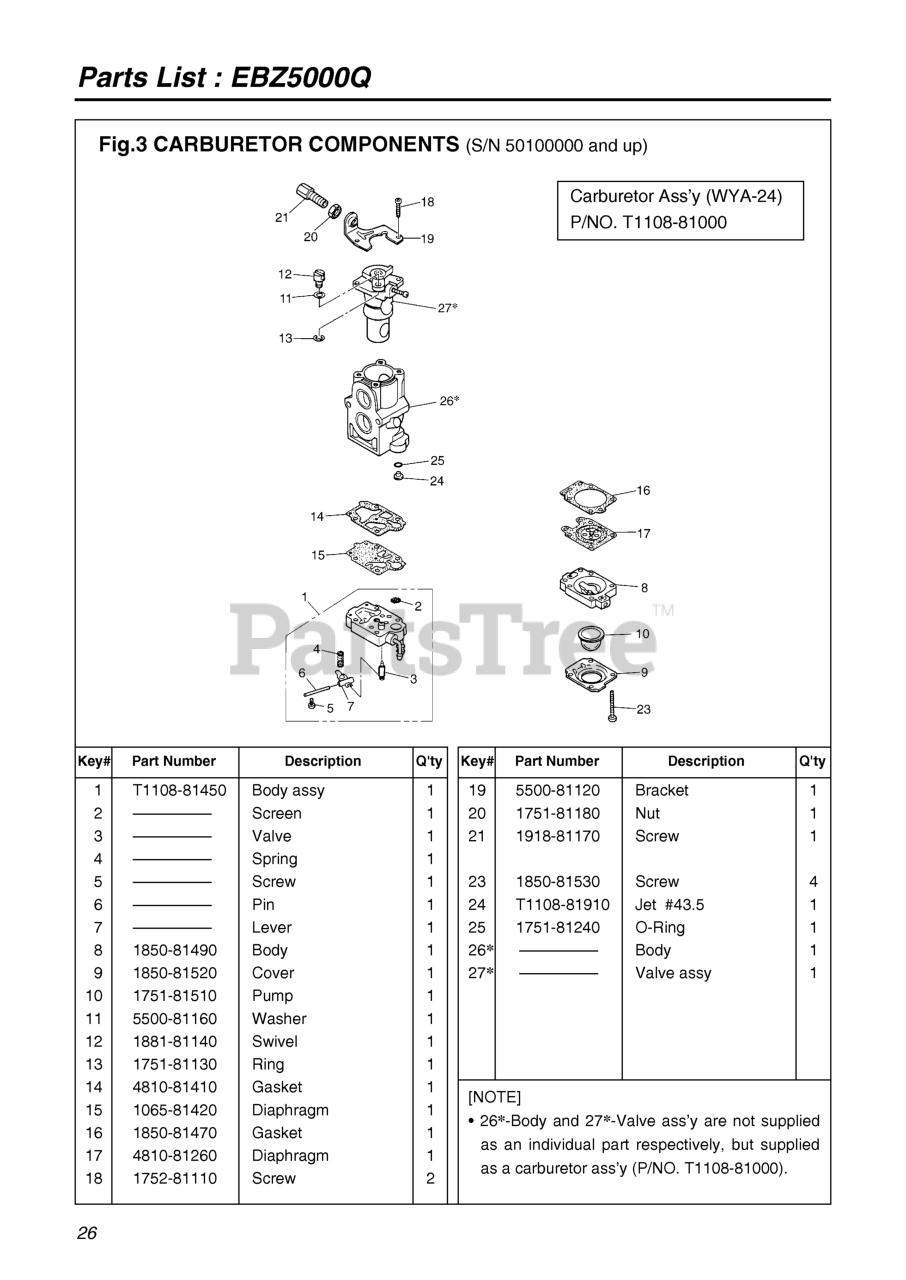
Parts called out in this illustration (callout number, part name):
1	BODY ASSY.
2	SCREEN
3	VALVE
4	SPRING
5	SCREW
6	PIN
7	LEVER
8	BODY, PURGE
9	COVER, PUMP
10	PUMP, PRIMING
11	WASHER
12	SWIVEL
13	RING
14	GASKET, PUMP
15	DIAPHRAGM
16	GASKET, DIAPHRAGM
17	DIAPHRAGM (RPLS 3310-81260)
18	SCREW
20	NUT, CABLE ADJUSTER
21	SCREW, CABLE ADJUSTER
23	SCREW
24	JET 43.5
25	RING, O
26	CARBURETOR (WYA 24A)
27	CARBURETOR (WYA 24A)
NI	CARBURETOR (WYA 24A)
